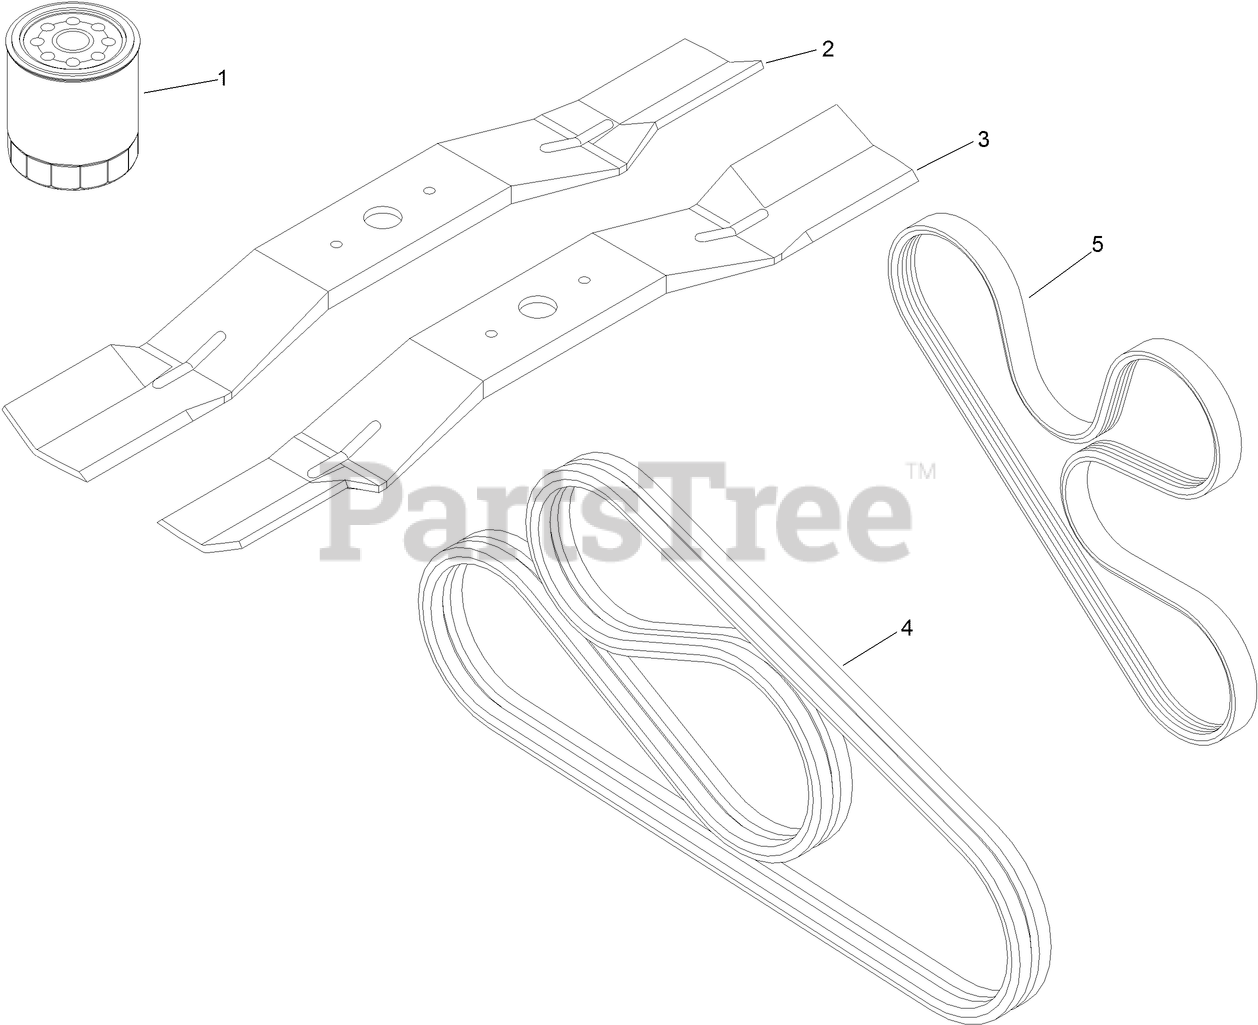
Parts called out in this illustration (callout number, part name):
1	ELEMENT-FILTER, 25 MICRON
2	BLADE-25IN, LH
3	BLADE-25IN, RH
4	BELTS-PAIR, MATCHED
5	BELT-V
